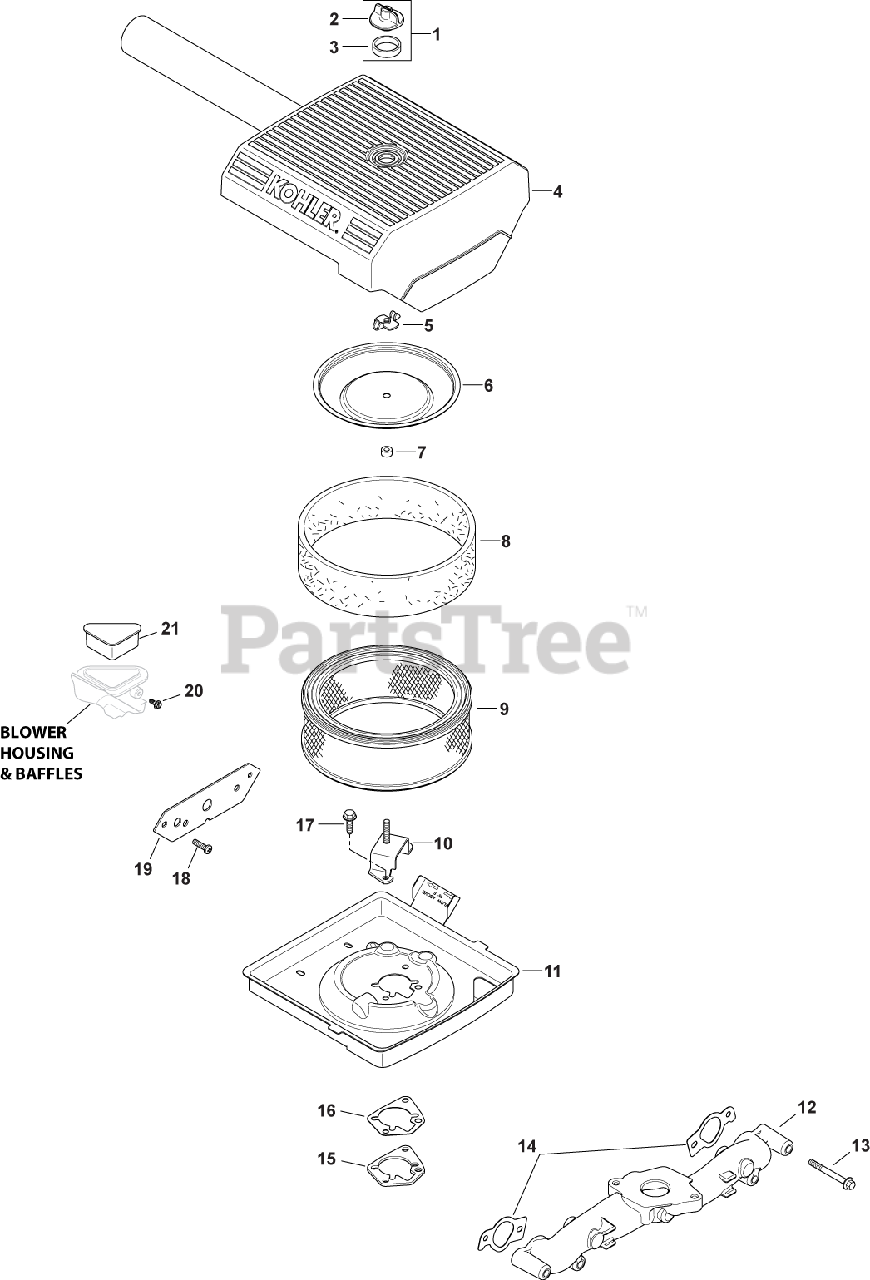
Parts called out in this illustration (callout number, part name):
1	KIT, KNOB W/SEAL
2	KNOB, COVER
4	COVER, AIR CLEANER
5	NUT, WING
6	COVER, INNER AIR CLEANER
7	SEAL, INNER AIR CLEANER
8	ELEMENT, PRECLEANER (LOW)
9	ELEMENT, AIR CLEANER - Also available Retail Packaged 47 883 03-S1 Air Filter Kit
10	BRACKET,AIR CLEANERBASE-USE 24 126 206-S
11	BASE ASSY, AIR CLEANER-USE 24 094 89-S
12	MANIFOLD, METAL INTAKE
13	SCREW, FLG M6X1.0X55
14	GASKET, INTAKE MANIFOLD USE 24 041 79-S
15	SPACER, AIR CLEANER
16	GASKET, AIR CLEANER BASE
17	SCREW,FLG THD FRM M6X1.0X20-(#25086396S)
18	SCREW, PHL HD 11-16X3/4"
19	PANEL, FRONT CONTROL
20	SCREW, WSH HD TAP #8-18X1/2"
21	COVER, BLOWER HOUSING USE 24 096 160-S
